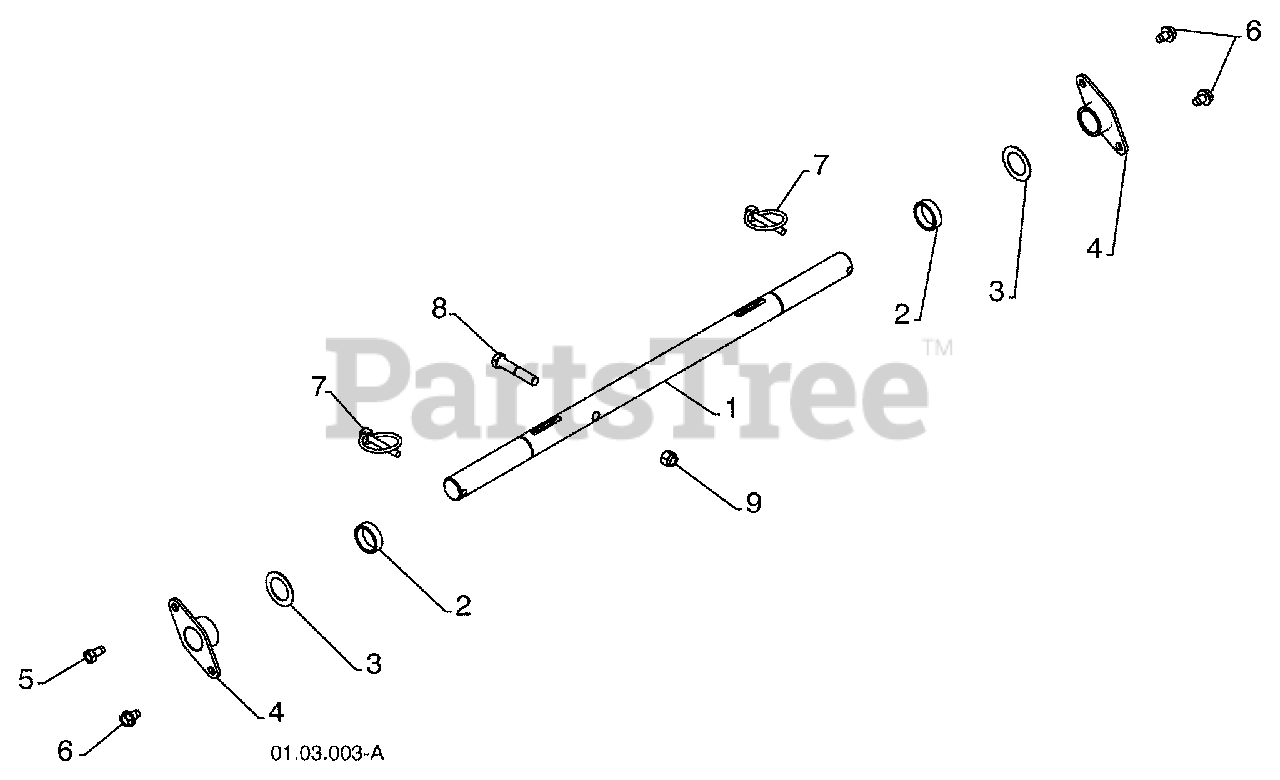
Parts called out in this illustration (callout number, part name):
1	AXLE SHAFT
3	THRUST WASHER
5	SCREW 5/16-18 X .625
6	BOLT 5/16-18 X .500
8	SCREW 3/8-16 X 2.00
9	NUT 3/8-16
